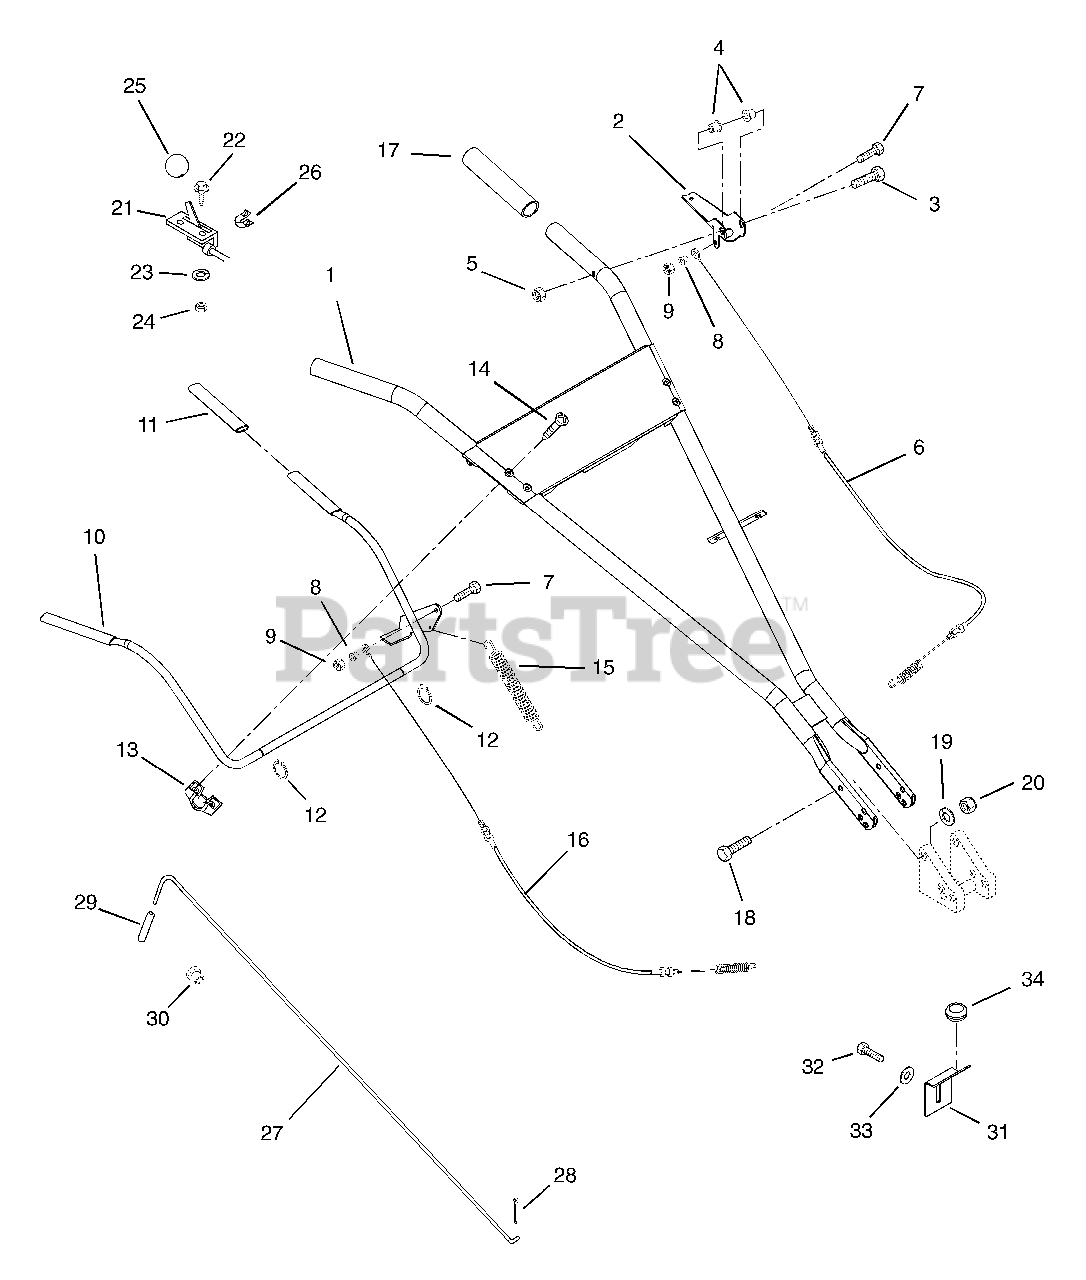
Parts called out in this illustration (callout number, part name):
1	HANDLEBAR WITH DECAL - RT8020
2	HANDLE, REVERSE
3	@BLT-HEX .31-18X2.25 GR5 YWZC
4	BSHG-FLG .325X.465X.333X.685
5	@NUT-LK-CTR .31-18 YWZC
6	CABLE, REV 8HP
7	@BLT-HEX .25-20X1.00 GR5 YWZC
8	BSHG-FLG .253X.373X.385X.500
9	@NUT-LK-CTR .25-20 YWZC
10	BAIL, FWD
11	GRIP, TILLER - OPC
12	RG-RTNG-EXT .500X.042 (E)
13	PIVOT, BAIL
14	SCR-TAP 12-24X1.50 CROVH YZ BT
15	SG-TENS .051X.50X4.87
16	CABLE, FWD
17	HANDLEGRIP
18	@BLT-HEX .38-16X1.00 GR5 YWZC
19	@WSHR-LK .38X.094 REG YWZC
20	@NUT-LK-CTR .38-16 YWZC
21	CONTROL, THROTTLE (BLK)
22	@SCR-MCH 10-24X.50 HWH YWZC
23	@WSHR-LK #10X.047 REG YWZC
24	@NUT-HEX 10-24 YWZC
25	KNOB, CONTROL-THROTTLE
26	CABLE RETAINER
27	ROD, POSITION
28	@PIN-CTR .12X.75 EXTPRSQCT YWZ
29	GRIP, BLACK
30	SNAP BUSHING
31	PIVOT FEED
32	@BLT-HEX .25-20X.75 GR5 YWZC
33	@WSHR-FL-STL.281X.62X.065 YWZC
34	GRMT .75X1.06X1.38
